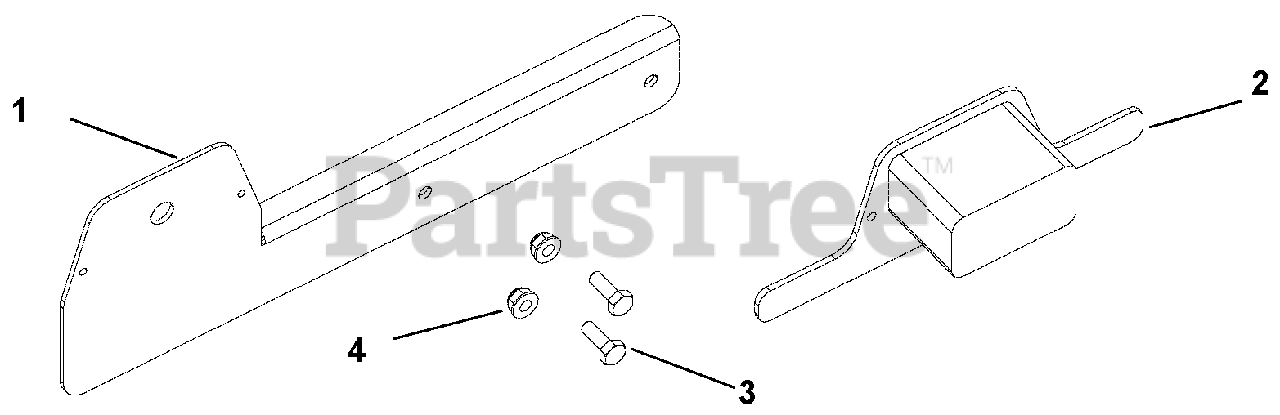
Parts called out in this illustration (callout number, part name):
1	BRKT, SPLITTER LICENSE PLATE
2	LICENSE PLATE BRACKET W/ LIGHT
3	@BLT-HEX .25-20X.75 GR5 YWZC
4	@NUT-LK-NYL-FLG .25-20 YWZC
